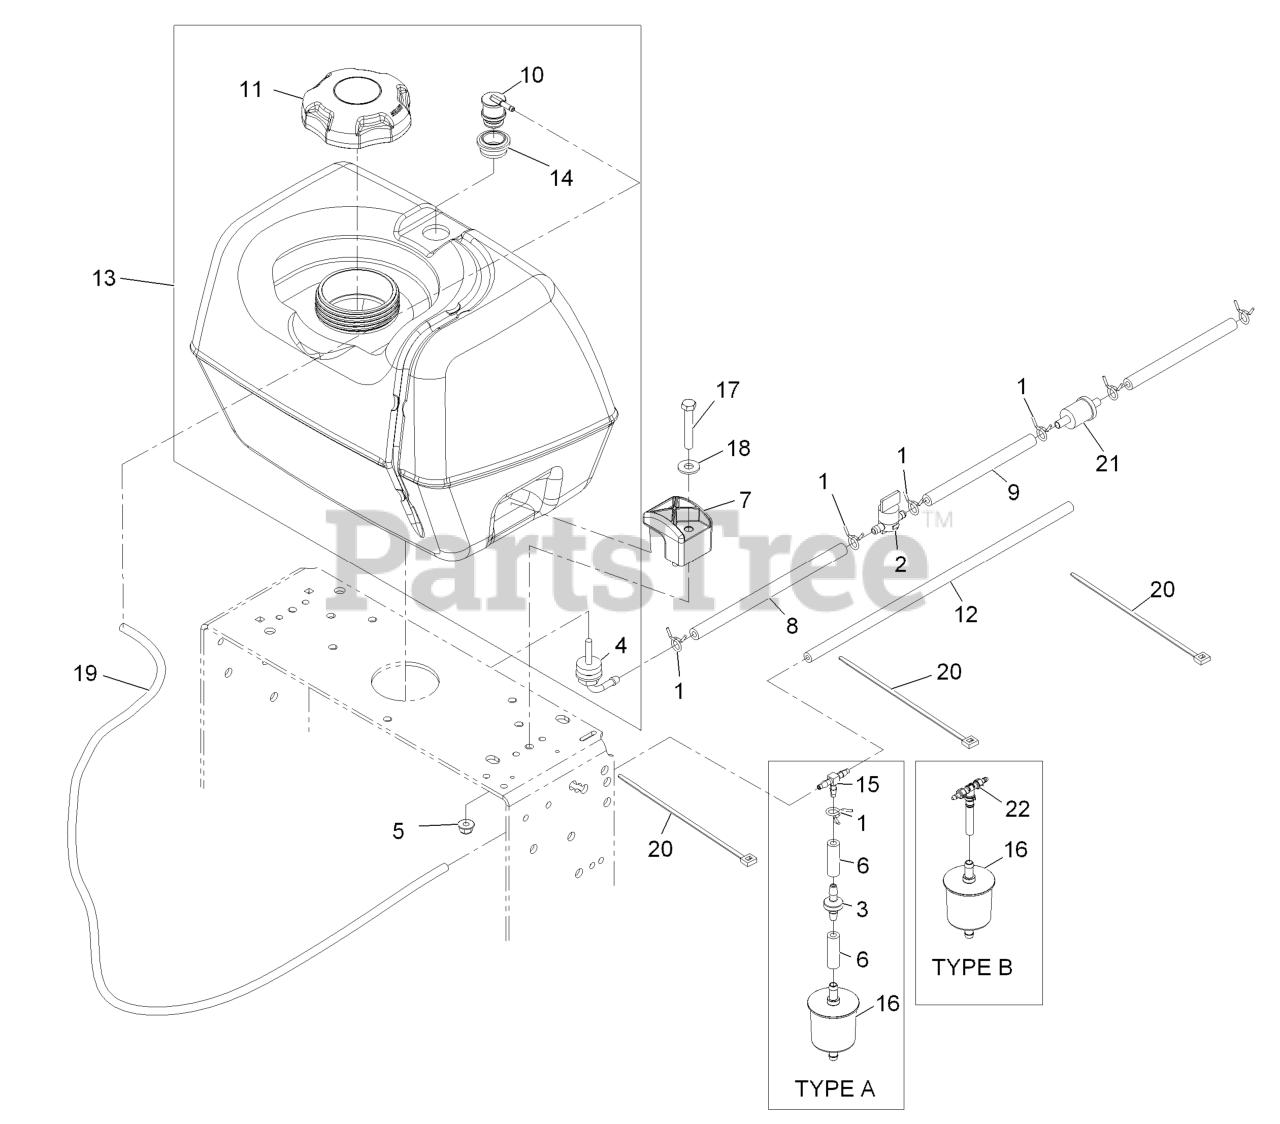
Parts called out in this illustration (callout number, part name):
1	CLAMP-HOSE
2	VALVE-FUEL
3	VALVE-CHECK, FUEL
4	FITTING-FUEL, BULKHEAD
5	NUT-HF, NI
6	HOSE-FUEL
8	HOSE-FUEL
9	HOSE-FUEL
12	HOSE-FUEL
14	GROMMET
15	FITTING-TEE
16	FILTER-FUEL
17	SCREW-HH
18	WASHER-FLAT
19	HOSE-EMISSIONS
20	TIE-PLASTIC
21	Pn 41019-1055 Filter W/6in Fuel Line
22	TEE AND CHECK
